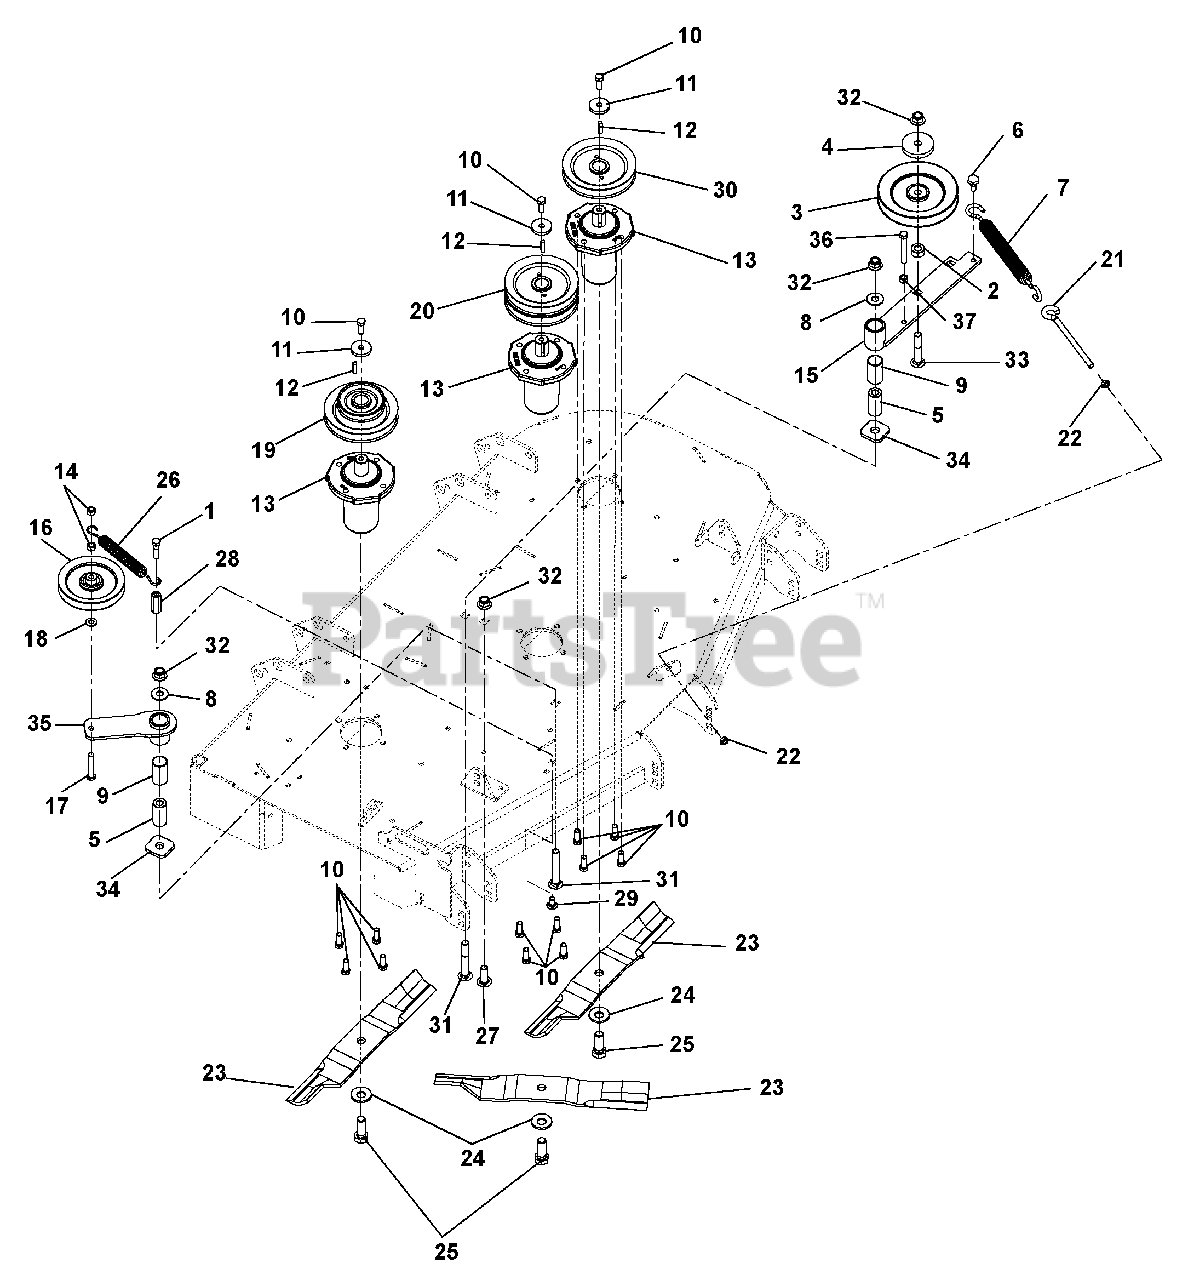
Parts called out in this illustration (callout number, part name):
1	BLT-HEX .38-16X1.50 GR5 YWZC
2	BSHG, SPCR .502X.997X.50 PM
3	PLY-V 6.0 X .500 ID SNGL BRG.
4	CAP, IDLER BEARING SEALING
5	BSHG, SPCR .502X.997X2.03 PM
6	BLT,SHLDR EP .38-16X.30 HEX YZ
7	SPRING, EXTENSION
8	WSHR-FL-STL .531X1.250X.10 YWZ
9	BSHG, 1.00 X 1.125 X 1.937
10	BLT-HEX .38-16X1.0 GR8 YZ EP30
11	WSHR,FLT STL.406X1.50X.245YWZC
12	KEY, SQ .25X.25X1.00 RC 40-50
13	ASSEMBLY, SPINDLE
14	NUT-LK-CTR .38-16 YWZC
15	WMT, IDLER ARM
16	SHV, .38"ID X 5.00"OD V-IDLER
17	BLT-HEX .38-16X2.25 GR5 YWZC
18	WSHR-FL-STL.406X.812X.065 YWZ
19	SHV,DBL 1,0"ID X 5.50"&3.50"OD
20	SHV,DOUBLE 1.0"ID X 5.50" OD
21	BOLT, .38-16X6.00 .62 DIA EYE
22	NUT-HEX-JAM .375-16 YWZC
23	BLADE, 16.19" MOWER (HI-LIFT)
24	WSHR-BLVL .669X1.535X.138
25	BLT-HEX .62-18X1.75 GR8 YWZC
26	SPRING, EXTENSION
27	BLT-RDHDSHSQNKFT.50-13X1.50 G5
28	NUT COUPLING .375-16X1.75
29	BLT-RDHDSHSQNK.38-16X1.0 G5YZ
30	SHV,SINGLE 1.0"ID X 5.50" OD
31	BLT-RDHDSQNK .50-13X3.50 G5YZ
32	NUT-LK-NYL-FLG .50-13 YWZC
33	BLT-RDHDSQNK .50-13X3.00 G5YZ
34	WSHR-FLT .640X1.75X.250
35	WMT, IDLER ARM
36	BLT-HEX .38-16X2.75 GR5 YWZC
37	NUT-HEX .38-16 YWZC
